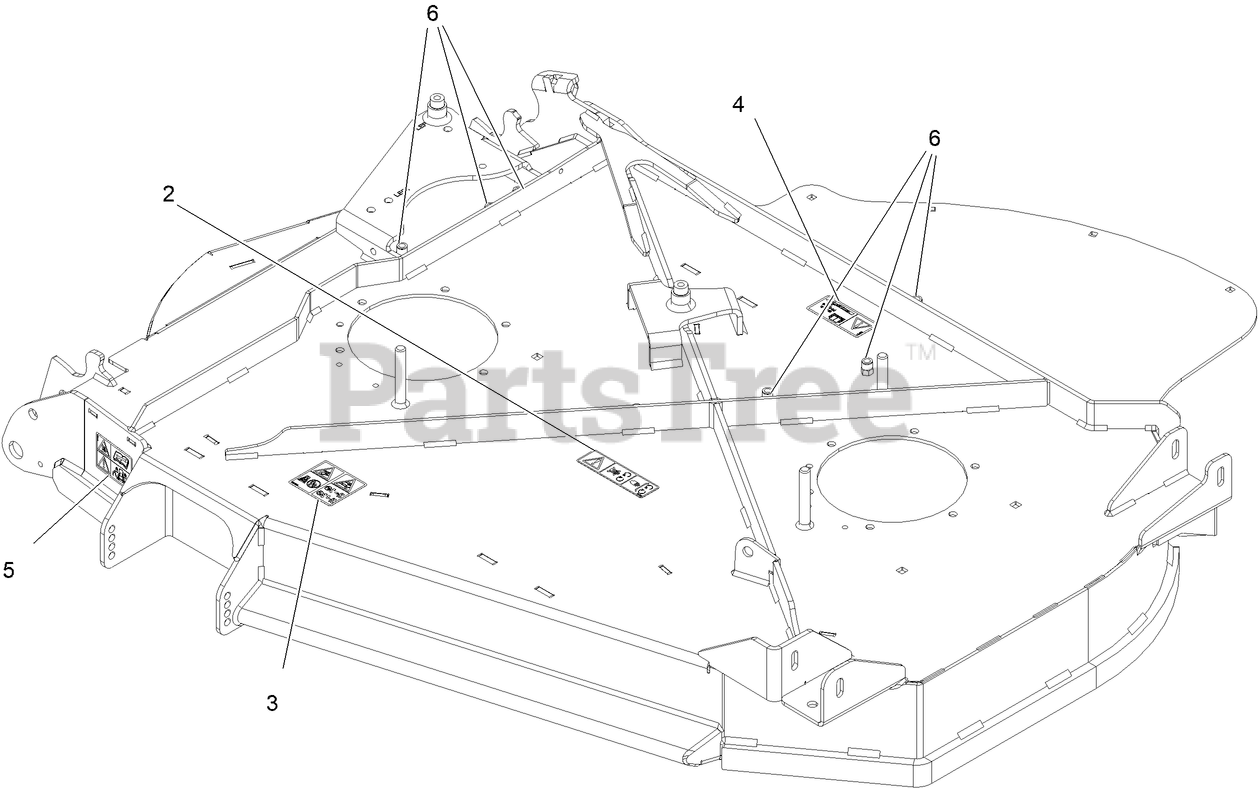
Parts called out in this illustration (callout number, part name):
2	DECAL-COVER, MISSING
3	DECAL-DANGER, THROWN OBJECT
4	DECAL-BOLT TORQUE
5	DECAL-WARNING, PINCH POINT
6	NUT-CLINCH,HEX
